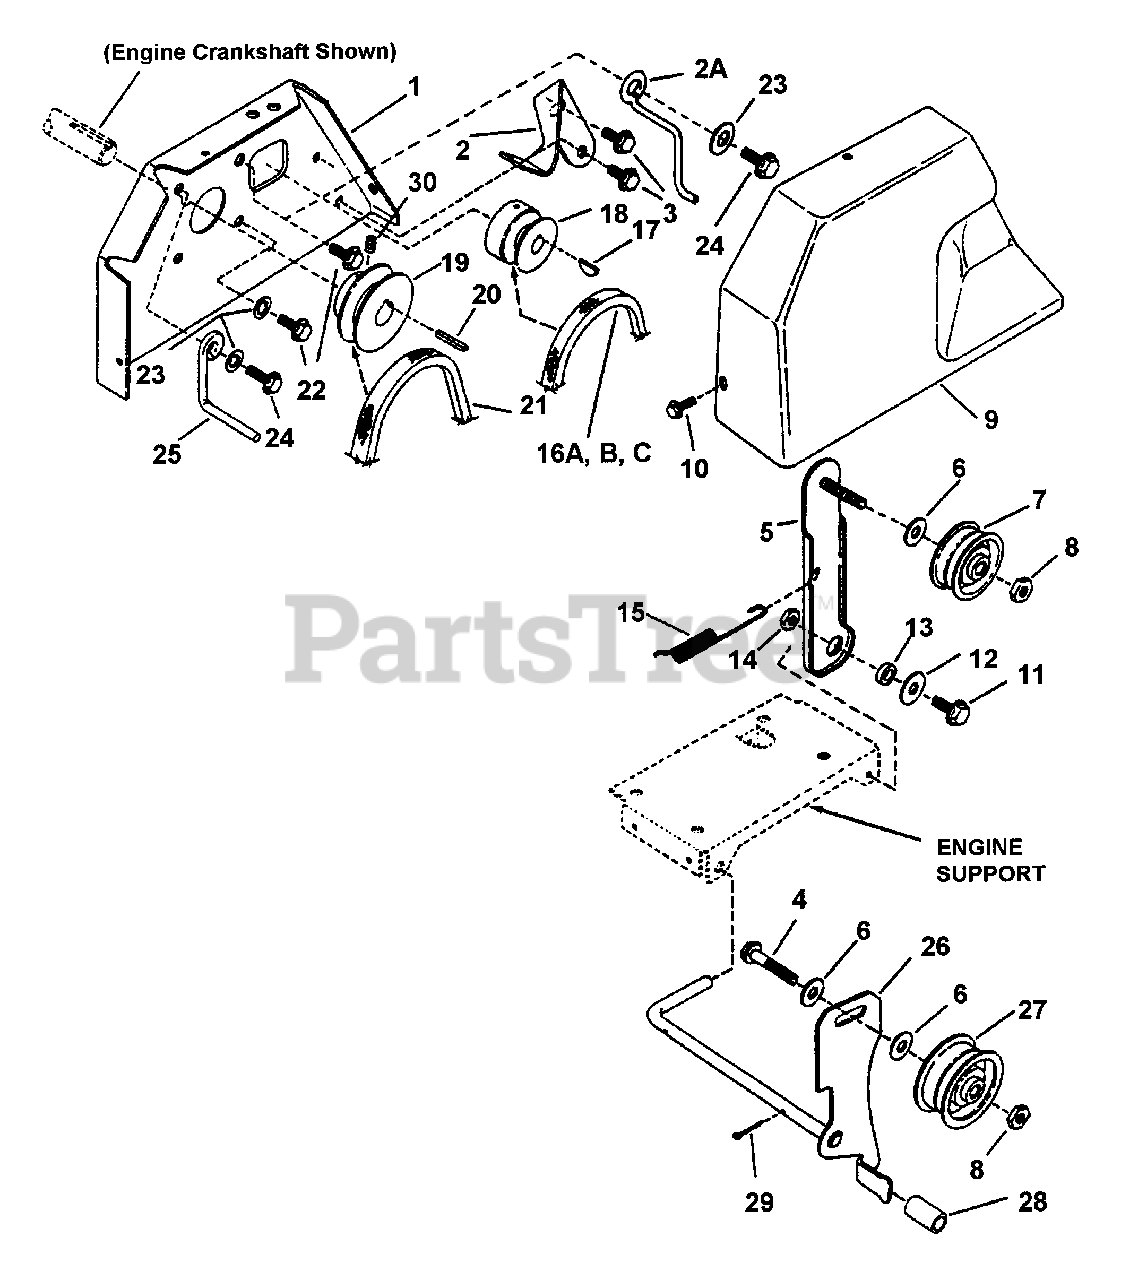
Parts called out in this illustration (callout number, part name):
1	PLATE, Engine
2	GUIDE, Belt
2A	GUIDE, Belt
3	SCREW, 5/16-18 x 1/2" Hex Head Cap
4	SCREW, 3/8-16 x 1-3/4" Hex Head Cap, Grade 5
5	BRACKET, Idler
6	WASHER, 3/8" Flat
7	IDLER, 2" O.D.
8	NUT, 3/8-16 Hex Center Lock, Grade B or 5
9	COVER, Belt
10	SCREW, #10-24 x 5/8" H. Wshr. Self-Tap, Gr. 5
11	SCREW, 5/16-18 x 1" Hex Head Cap, Grade 5
12	WASHER, 5/16" Flat
14	NUT, 5/16-18 Hex Center Lock, Grade 8 or 5
15	SPRING
16A	BELT, Traction
16B	BELT, Traction
16C	BELT, Traction
17	KEY, 1/8 x 5/8" Woodruff
18	PULLEY, P.T.O.
19	PULLEY, Auger Drive
20	KEY, 3/16x3/16x1"
21	BELT, Blower
22	SCREW, 5/16-24 x 1/2" Hex Head Cap
23	WASHER, 5/16" Internal Tooth Lock
24	SCREW, 5/16-24 x 3/4" Gr. 5
25	GUIDE, Belt
26	BRAKE ARM & ROD
27	IDLER, 2-1/2" Flat
28	TUBE, Brake
29	PIN, 1/16 x 3/4" Cotter
30	SCREW, 1/4-20 x 5/16 Socket Set
